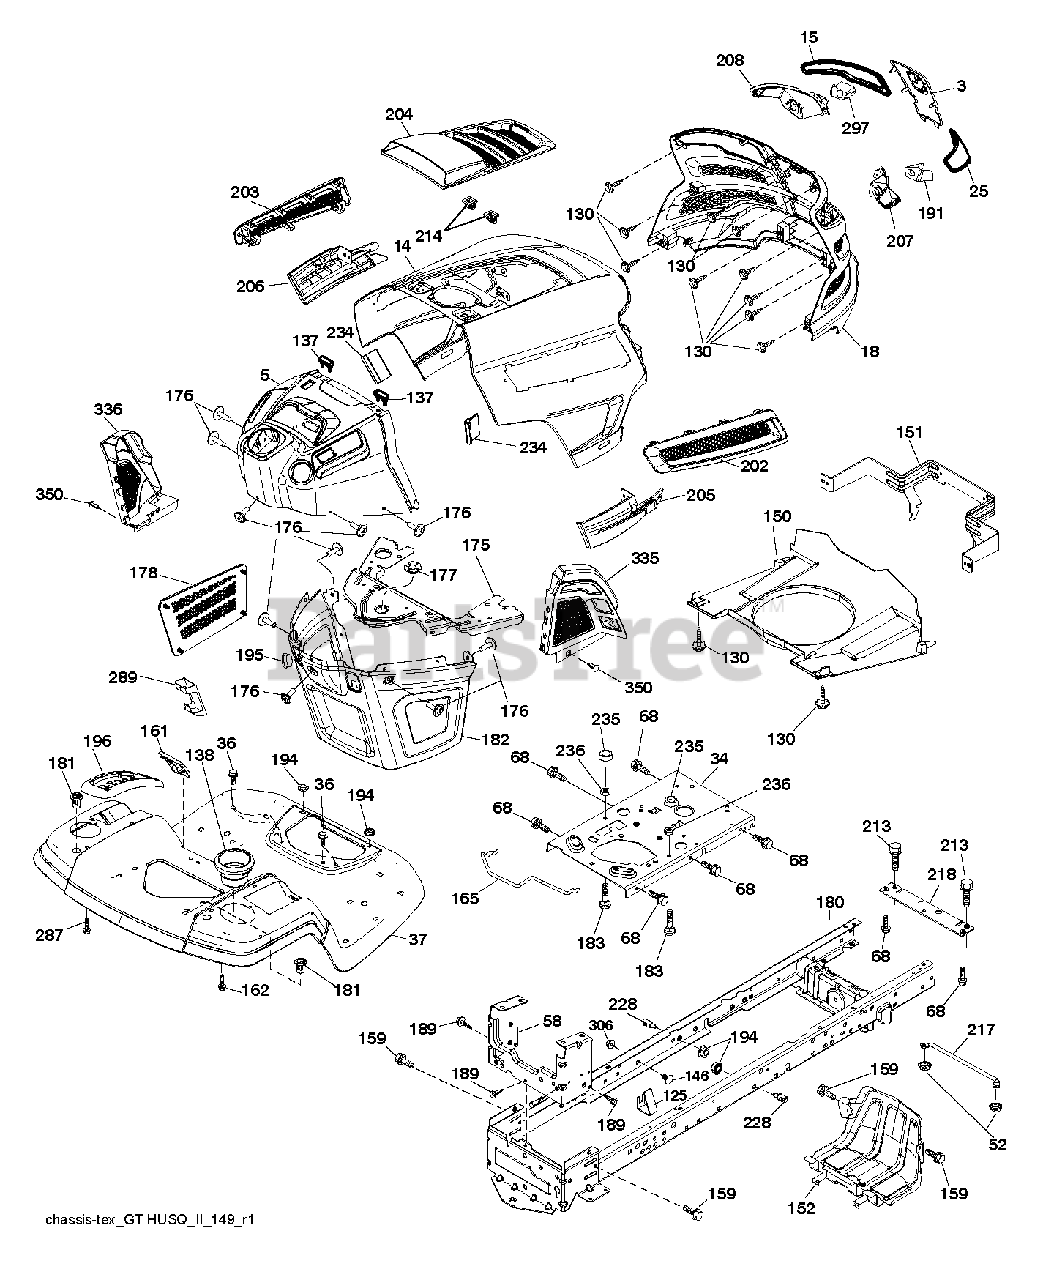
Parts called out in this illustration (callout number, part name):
3	APPLIQUE.SUBASM.GT.HUSQ.II
5	DASH.UPPER.ASSY.GT2.GREY
14	HOOD.ASM.HUSQVARNA.GT.TEX.ORAN
15	LENS.HEADLIGHT.LH.GTII.2011
18	GRILLE.SUBSTRATE.2011.
25	LENS.HEADLIGHT.RH.GTII.2011
34	PLATE.ENGINE.WELDED.CHASSIS
36	SCREW 5/16"
37	FENDER.TLT.FS.W/CPH/FW/RSF.668
52	LOCKNUT
58	DRAWBAR UPPER 2PC SMALL FENDER
68	SCREW LT
125	CLIP.FUEL.LINE
130	SCREW.#10 X 0.750.BOS
137	BUMPER DASH
138	HOLDER.CUP.LT.GREY
146	BOLT.RDHD.SHT.SQNK.3/8-16X5/8
150	AIR.DUCT.GTV2(2.54"RING HEIGHT
151	BRACKET.PIVOT.HOOD.GT.HUSQ.II
152	SHIELD.BROWNING.PNT.GT.V2
159	SCREW, 3/8-16X3/4
161	WINDOW.FUEL.LT.TEX.GREY
162	SCREW.HI-LO.CONSOLE
165	SUPPORT.TANK.REAR.W/TEX
175	PLATE.CROSSMEMBER.HUSQ
176	SCREW.#10-24X5/8.RN.QU
177	BUSHING, STEERING
178	CARGO.ASM.NET.TXGT.W/C
180	CHASS.WLDMNT.TL.12GA/2P.48/54
181	BUSHING.MNT.FEND.CRGO.TEX.49
182	DASH.LOWER.COMMON.12V.ADAPTOR
183	BOLT.5/16-18X1-1/4 FULL THD
189	SCREW
191	INSERT.REFLECTIVE.RH.HUSQ.GTII
194	NUT LOCK HEX FLANGE 5/16-18
195	PLUG.HOLE.DASH.LOWER.12V.BLK
196	DECKLFT.CONSOL FULL ASSM GREY
202	VENT.SIDE.RH.GT.HUSQ.II.
203	VENT.SIDE.LH.GT.HUSQ.II.498
204	VENT.TOP.HUSQ.GT2
205	SIDE.TRIM.RH.GT.HUSQ.II
206	SIDE.TRIM.LH.GT.HUSQ.II.GRAY
207	BEZEL LIGHT.RH.GT.II.MYLAR
208	BEZEL LIGHT.LH.GT.II.MYLAR
213	BOLT
214	CLIP.RETAINER.TINNER.
217	ROD.PIVOT.HOOD
218	X-PIECE.HOOD.STOP.NON/
228	STUD.FASTNER.W/ANTI-ROTATE
234	BUMPER.HOOD.TEX.HUSQVARNA
235	SPACER FENDER
236	NUT.CENTERLOCK.5/16-
287	SCREW 1/4X20
289	PLUG.N/CRUISE.COMMON.YT/GT.BLK
297	INSERT.REFLECTIVE.LH.HUSQ.GTII
306	NUT LOCK FLG 3/8-16 UNC
335	COVER.RH.CLOSE.OUT.BLACK
336	COVER-LH.LOWER.DASH.GT2.BLACK
350	CLIP.X-MAS.TREE
